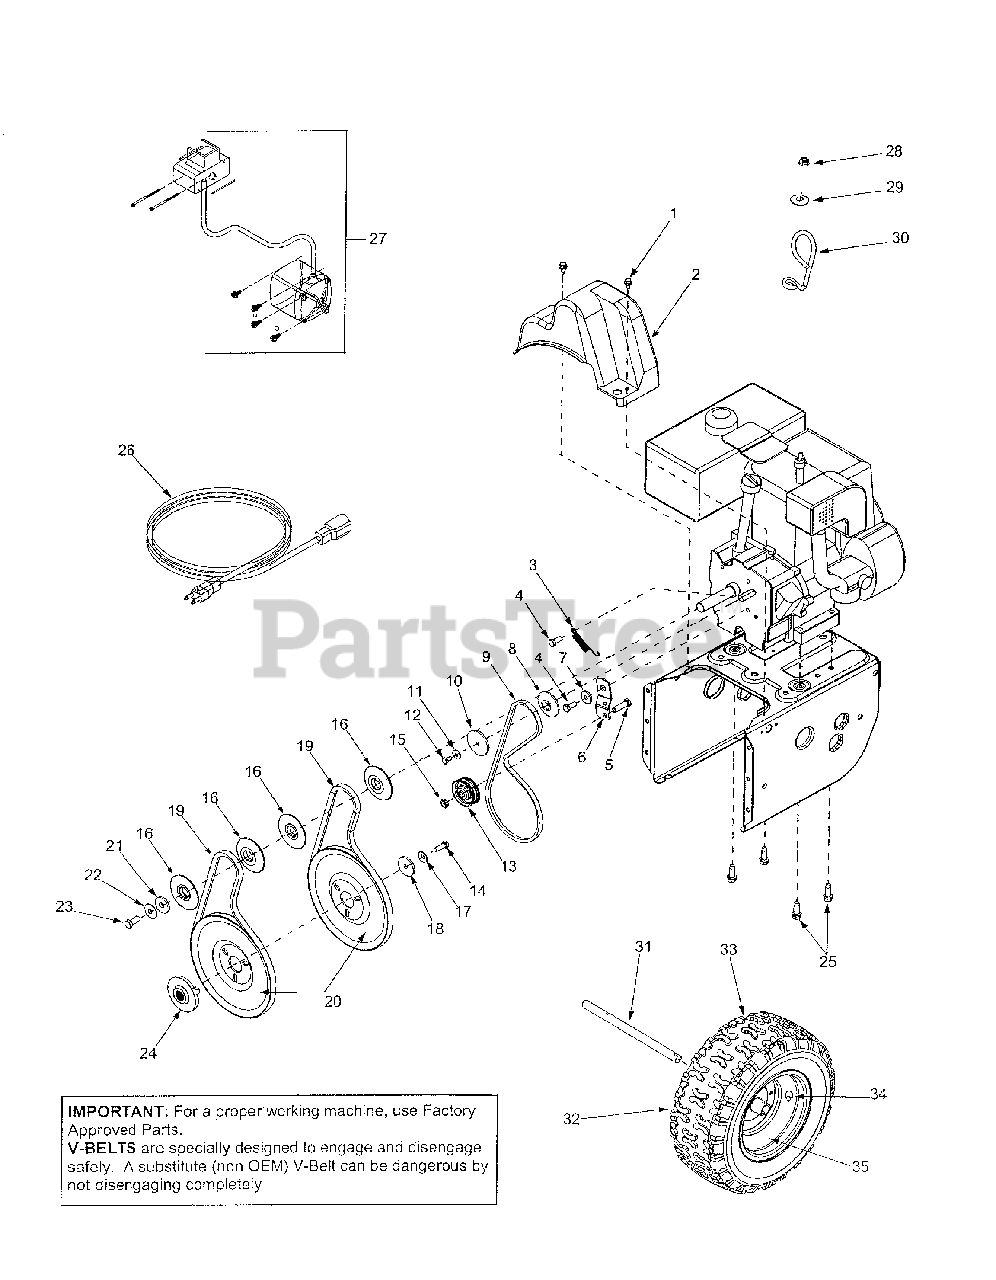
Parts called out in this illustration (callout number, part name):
1	Hex Washer Screw 1/4-20 x .625
2	Belt Cover
3	Extension Spring
4	Hex Screw 5/16-24 x .75
5	Hex Cap Screw 3/8-16 x 1.25
8	Pulley Half
9	V-Belt
10	Pulley Half
11	Bell Washer
12	Hex Cap Screw 1/4-28 x .50
13	Flat Idler
14	Lock Hex Cap Screw 5/16-24
15	Lock Jam Nut 3/8-16
16	Pulley Half
17	Bell Washer
18	Flat Washer
19	Belt
20	Auger Pulley
21	Flat Washer 3/8 x 1.25 OD
22	Bell Washer
23	Hex Cap Screw 3/8-24
24	Adapter Pulley
25	Hex Screw 3/8-16 x 1.0
26	Extension Cord
27	Electric Start Kit
28	Lock Nut, 1/4-20
29	Flat Washer, .28 x .74 x .063
30	Cable Guide
31	Axle: .75 dia. x 12.2" Lg.
34	Tubeless Air Valve
